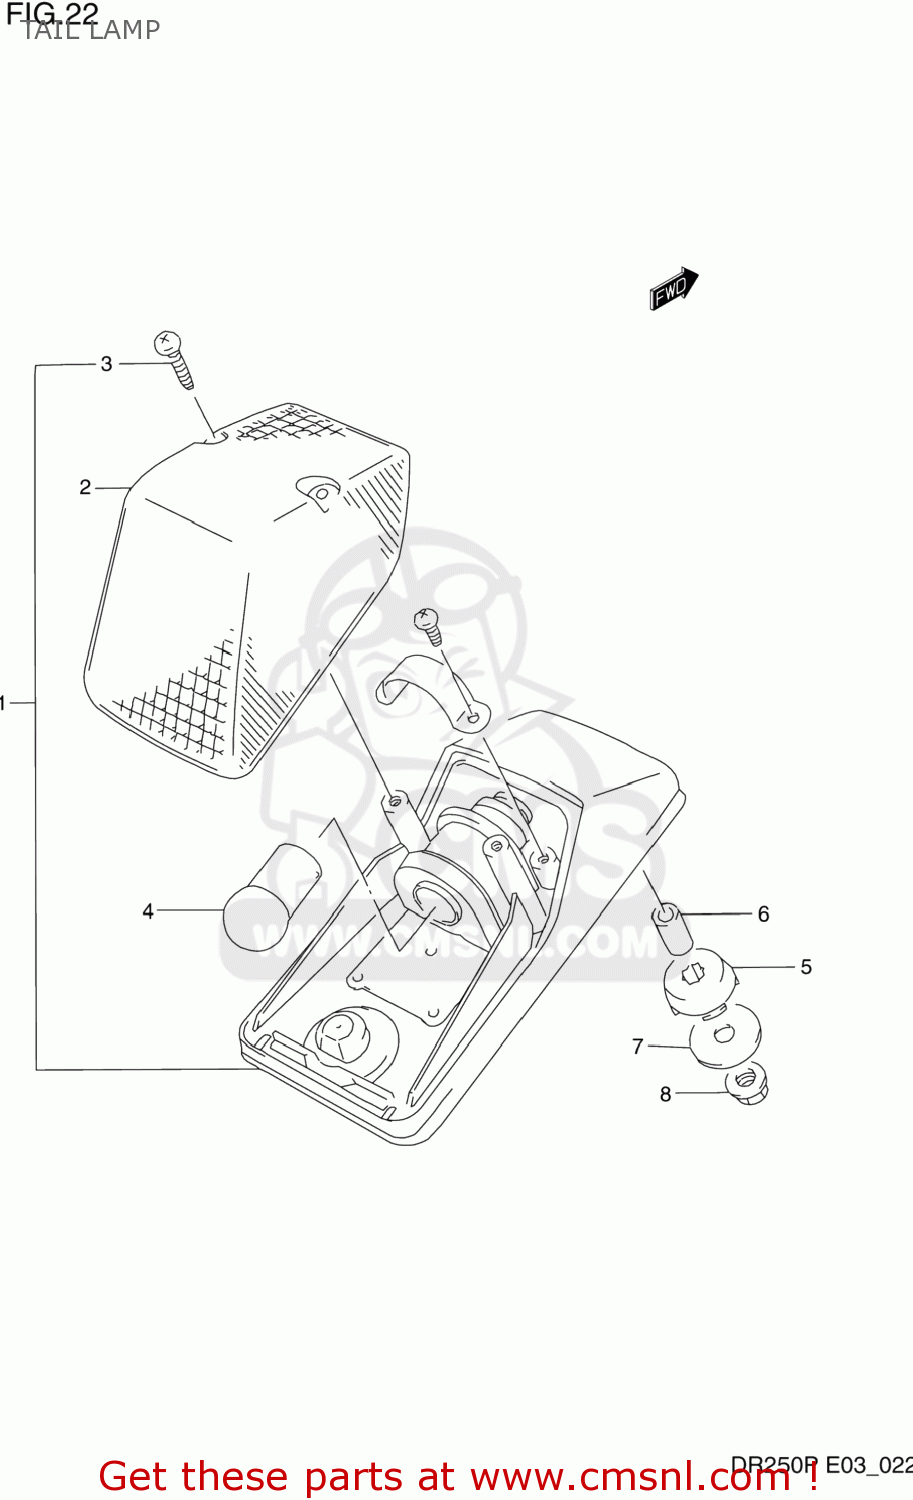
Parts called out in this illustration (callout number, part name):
1	LAMP ASSY,TAIL
2	LENS
3	SCREW
4	BULB(12V5W,BF150-40160A)
5	CUSHION
6	SPACER(6.4X9.2X12)
7	WASHER
8	NUT
